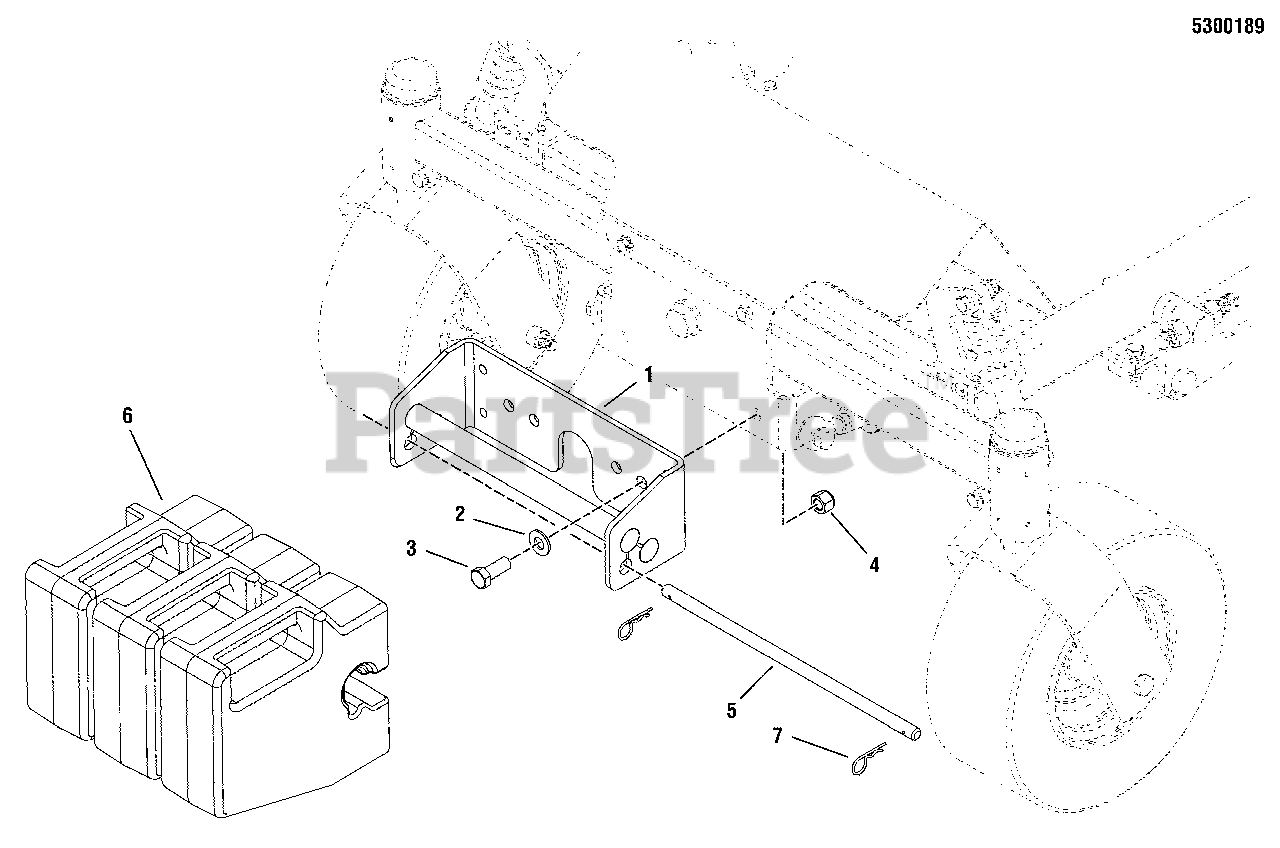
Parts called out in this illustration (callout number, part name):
1	HOLDER ASMY-WEIGHT CONS Z CAT - BLACK
2	WASHER, 1/2 SAE
3	BOLT, 1/2-20 X 1-1/4" GD5 YZ
4	NUT, 1/2-20 HEX NYLON LOCK
5	ROD-.500DIA 13.75LG YELLOW CON
6	WEIGHT-QUICK ATTACH 33LBS PAINTED BLACK
6	WEIGHT-QUICK ATTACH 50LB SUITCAS PAINTED
7	PIN, HAIR, .0915 X 1-7/8
